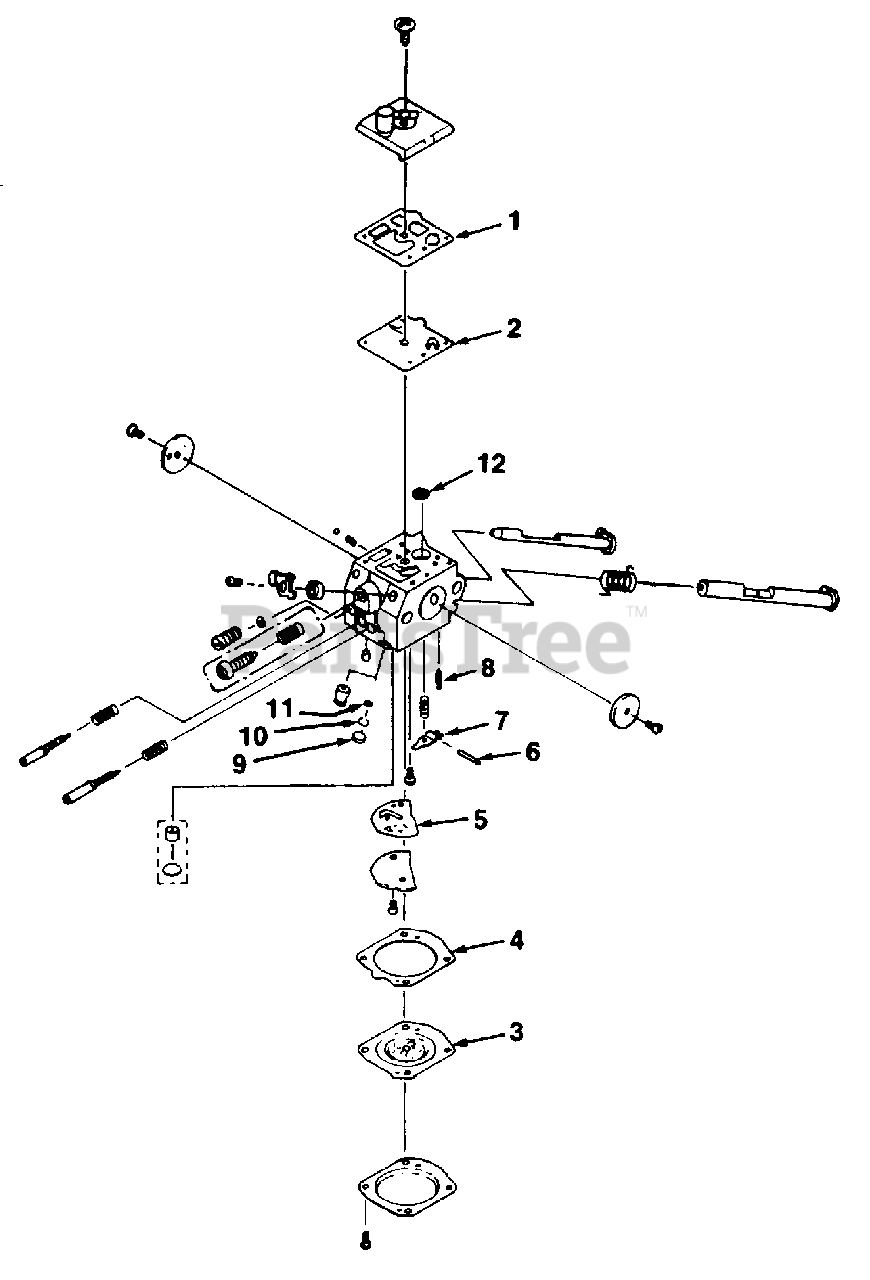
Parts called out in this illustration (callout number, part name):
1	Repair Kit (Includes 1-12)
2	Repair Kit (Includes 1-12)
3	Repair Kit (Includes 1-12)
4	Repair Kit (Includes 1-12)
5	Repair Kit (Includes 1-12)
6	Repair Kit (Includes 1-12)
7	Repair Kit (Includes 1-12)
8	Repair Kit (Includes 1-12)
9	Repair Kit (Includes 1-12)
10	Repair Kit (Includes 1-12)
11	Repair Kit (Includes 1-12)
12	Repair Kit (Includes 1-12)
